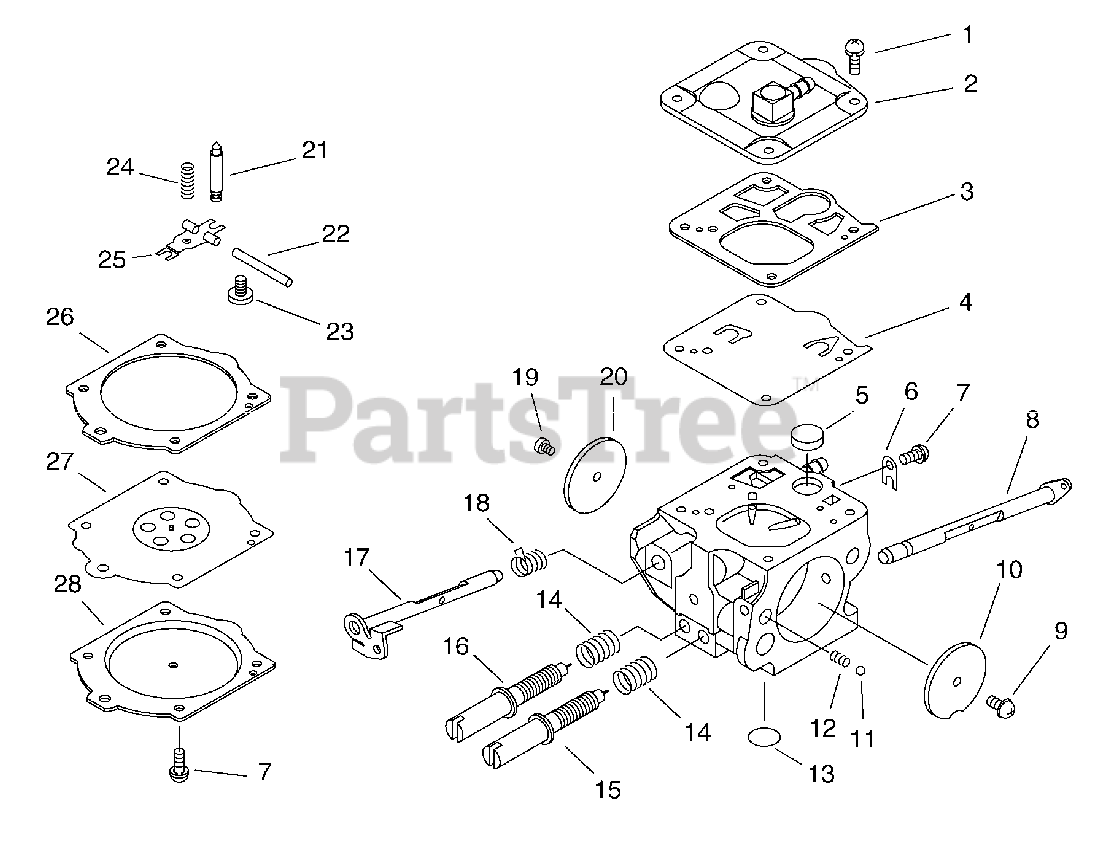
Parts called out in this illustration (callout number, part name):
1	SCREW, PUMP COVER
2	COVER, FUEL PUMP
3	GASKET, PUMP
4	DIAPHRAGM, PUMP
5	STRAINER
6	CLIP, THROTTLE SHAFT
8	SHAFT, CHOKE
10	VALVE, CHOKE
11	BALL, CHOKE
12	SPRING
13	PLUG, WELCH
15	NEEDLE - HIGH SPEED
16	NEEDLE - LOW SPEED
17	SHAFT, THROTTLE
20	VALVE, THROTTLE
21	VALVE, INLET NEEDLE
22	PIN, METERING LEVER
23	SCREW, METERING LEVER PIN
24	SPRING, METERING LEVER
25	LEVER, METERING
26	GASKET, METERING
27	DIAPHRAGM, METERING
28	COVER, METERING
